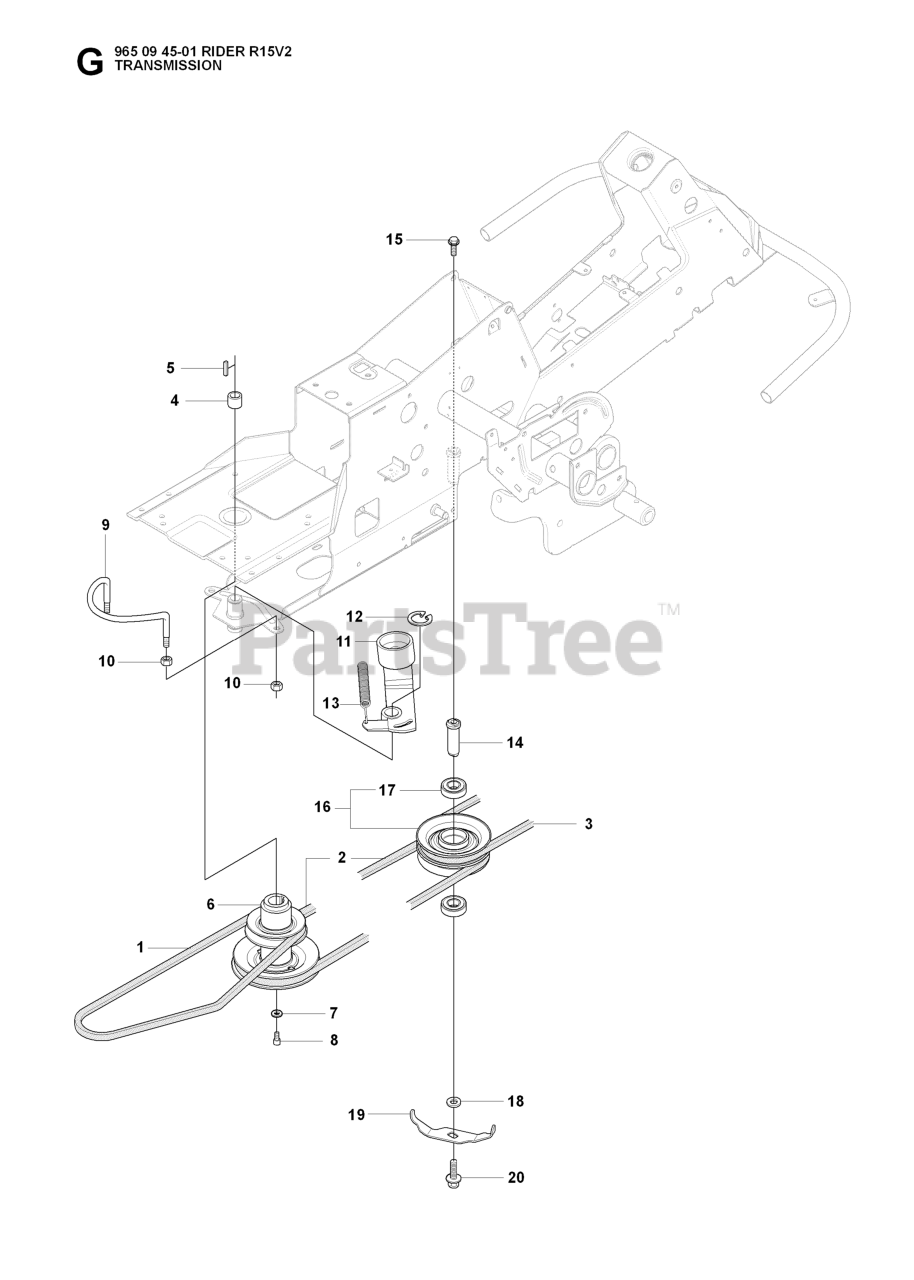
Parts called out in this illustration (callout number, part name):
1	BELT
2	BELT
9	BELT GUIDE
10	NUT
12	RETAINING RING SGA 25
14	SHAFT
18	BELT GUIDE
19	BOLT
